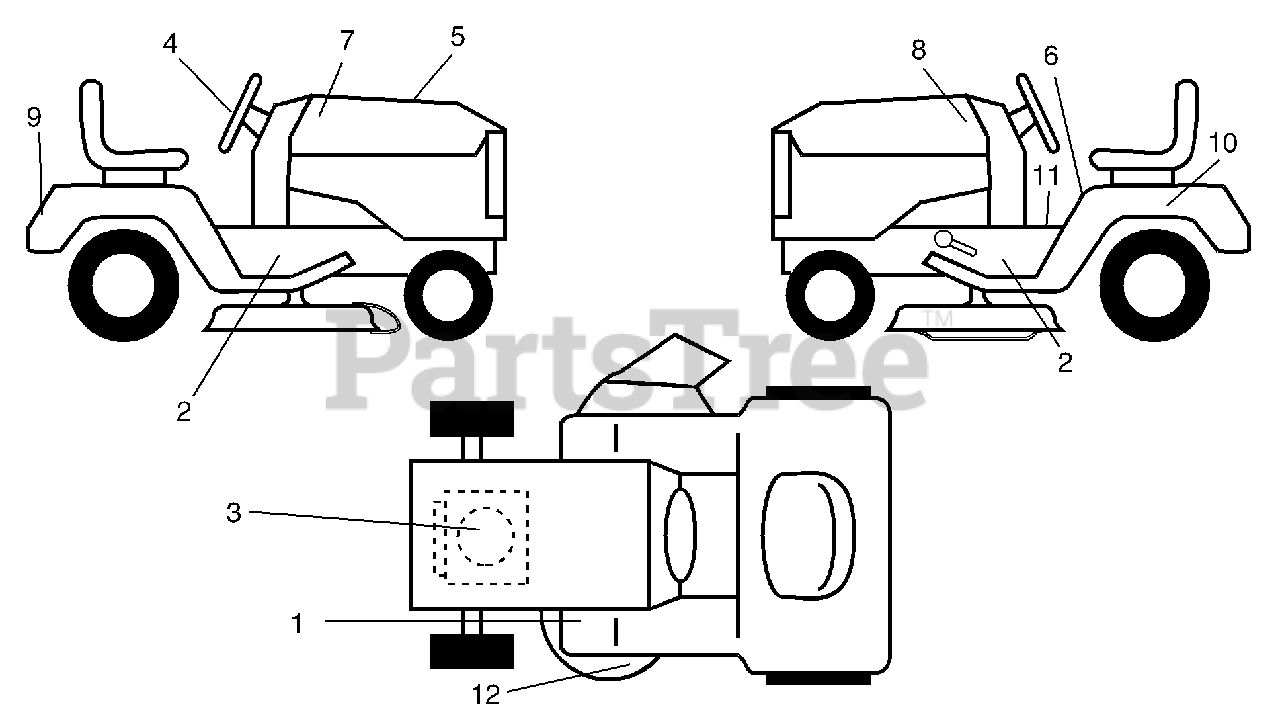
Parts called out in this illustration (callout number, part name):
1	Decal, Clutch/Brake
2	Decal, Chassis Agway
3	Decal, Engine HP
4	Decal, Steering Agway
5	Decal, Replacement
6	Decal, Fender Danger English
7	Decal, Hood RH Agway
8	Decal, Hood LH Agway
9	Decal, Fender Agway
10	Decal, Caution, Battery
11	Decal, Oper Sdl P/L Gear Dr
12	Decal, V-Belt Sch.
